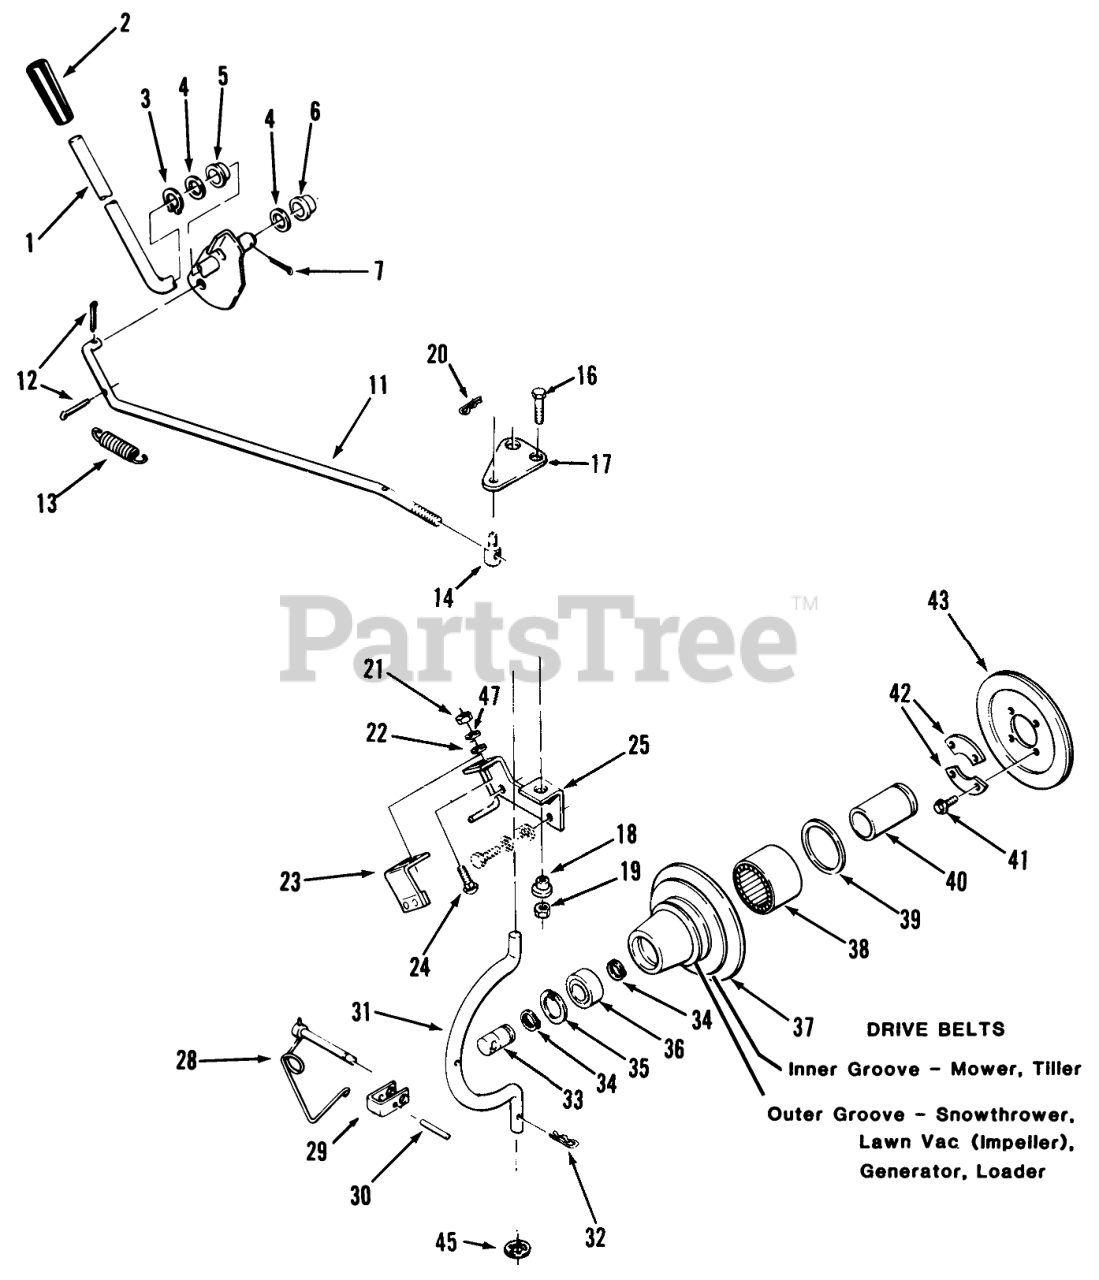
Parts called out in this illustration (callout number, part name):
1	Lever-Clutch,PTO
2	GRIP
3	RING-EXT GRIP
4	SHIM-WASHER
5	BUSHING-NYLINER
6	NYLINER BUSHING
7	PIN-COTTER
11	ROD-PTO CLUTCH
12	PIN-COTTER
13	SPRING
14	TRUNNION
16	SCREW-HH
17	PLATE
18	SPACER-LIFT LINK
19	NUT-LOCK, NI
20	Hairpin Cotter
21	Nut
22	WASHER-FLAT
23	ASM-Bracket
24	Bolt-Carriage
25	Bracket-Engine
28	LOCKING PIN ASM
29	CLEVIS
31	ROD-HOUSING
32	Hairpin
33	SHAFT-PTO
34	RING-SNAP, EXTERNAL
35	Ring-Snap
36	BEARING-BALL
37	Housing-Clutch
38	BRG-NEEDLE OPEN END
39	SEAL-OIL
40	RACE-BEARING
41	H H C S
42	RETAINER
43	Facing-Clutch
45	RING-REINFORCED CIRC
47	WASHER-LOCK
